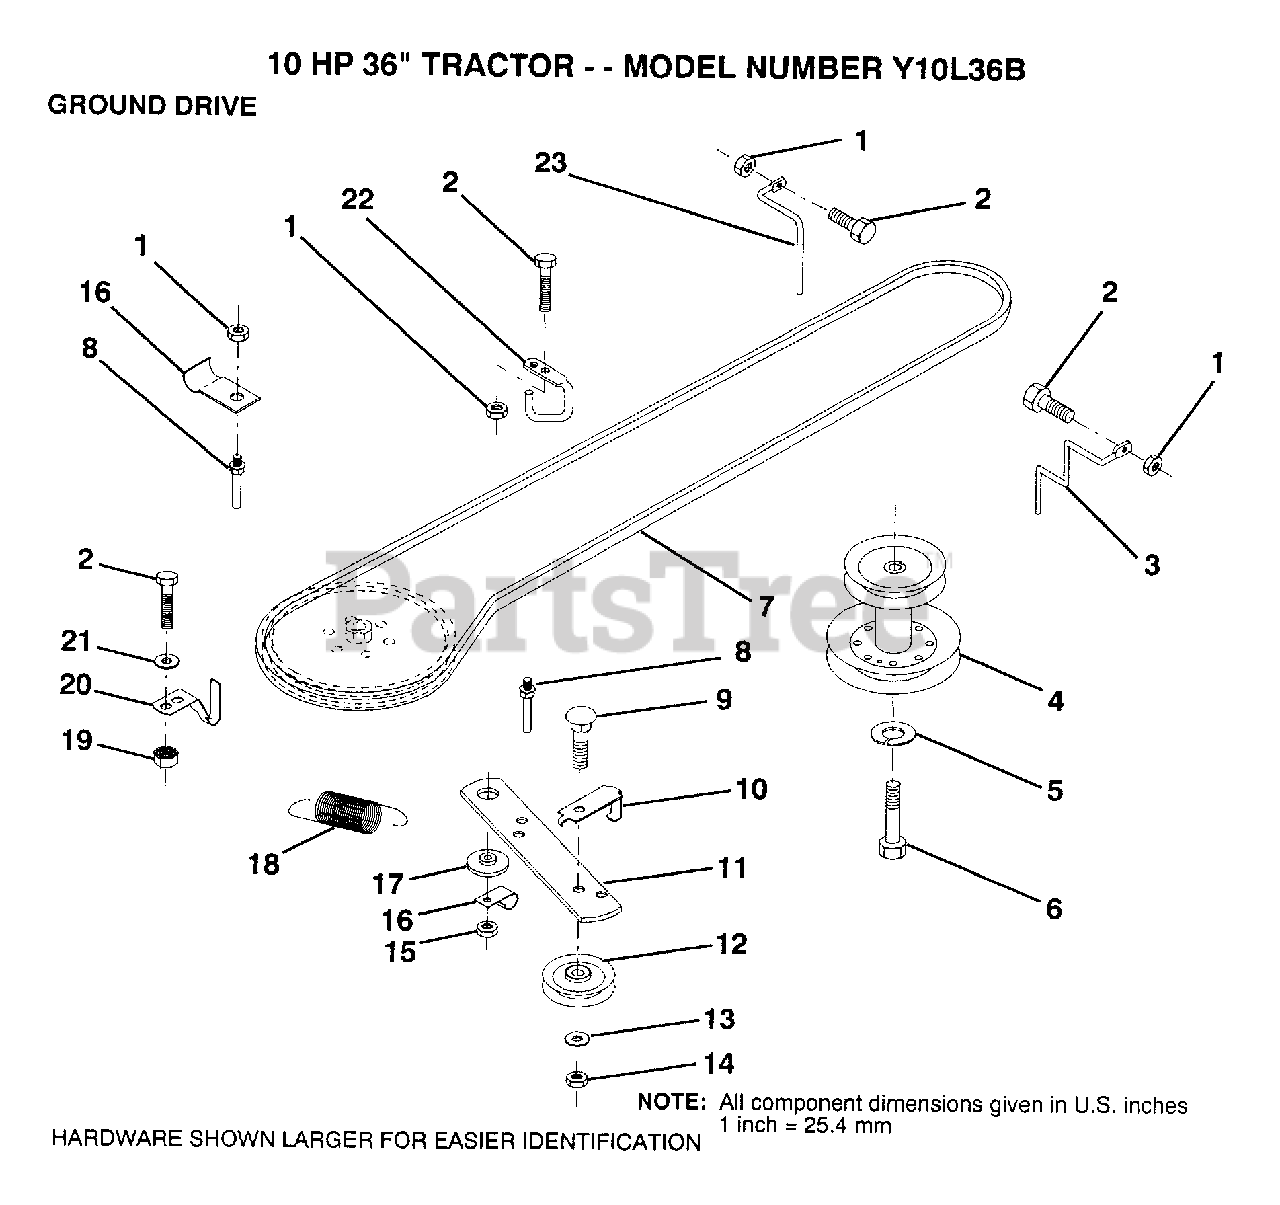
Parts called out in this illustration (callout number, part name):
2	BOLT
5	LOCKWASHER
6	HEX BOLT
7	BELT
8	"KEEPER,DRIVE BELT"
9	BOLT
10	"KEEP,IDLER DR BEL"
13	WASHER
14	LOCKNUT
16	"CLIP,INSULATOR"
17	SPACER RETAINER
20	"KEEPER,DR BELT "
21	WASHER
22	"KEEPER,FRA DR BEL"
